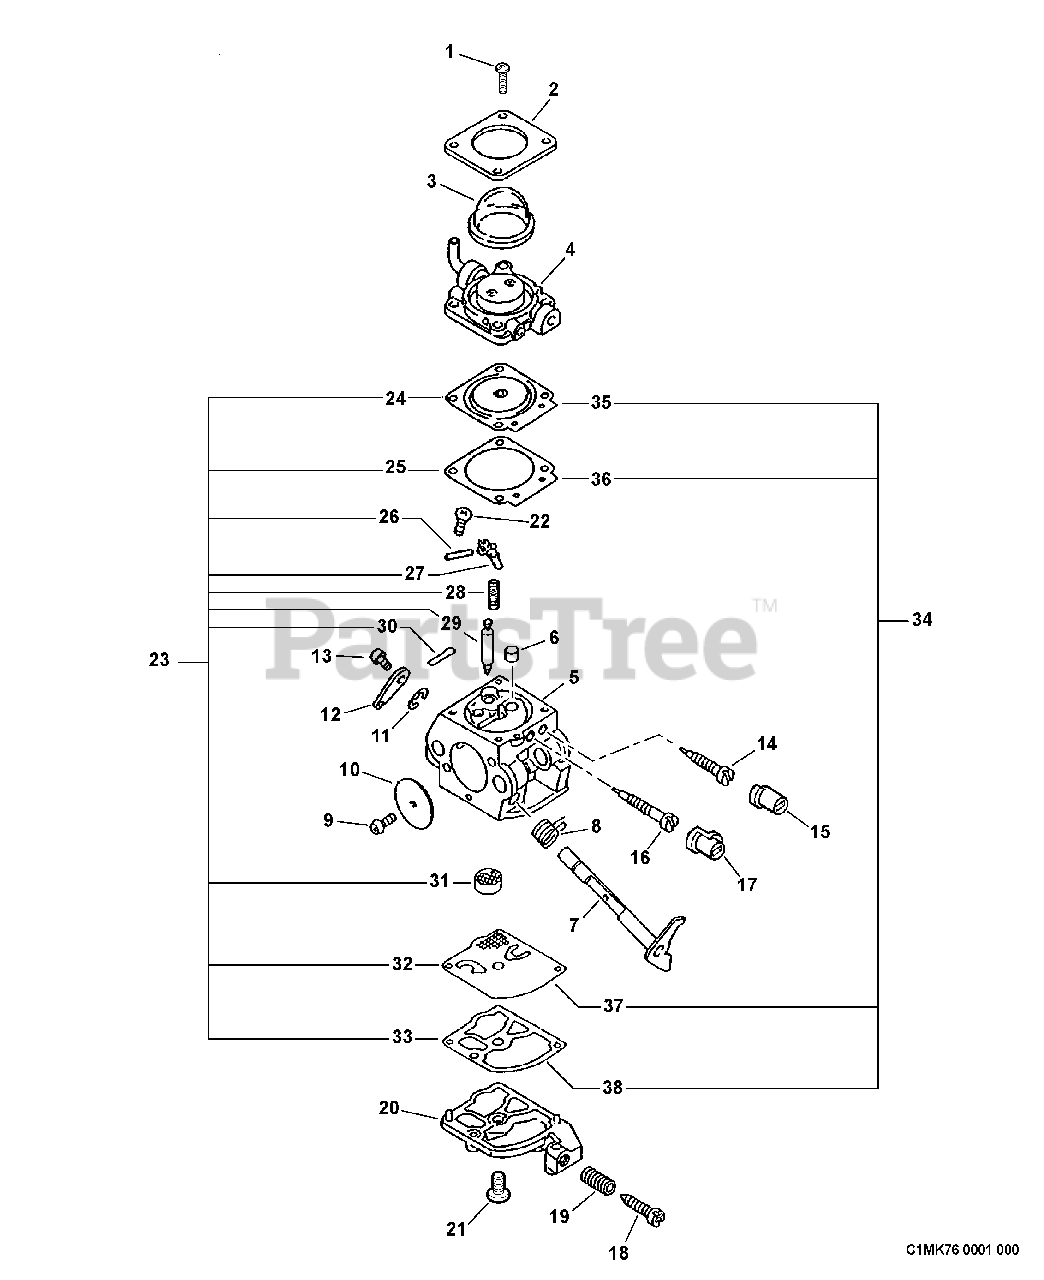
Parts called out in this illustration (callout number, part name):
1	SCREW, RETAINER
2	RETAINER, PURGE BULB
3	BULB, PURGE
4	BASE, PURGE
5	BODY, CARBURETOR
6	NOZZLE, CHECK VALVE
7	SHAFT, THROTTLE
8	SPRING, TRIGGER
10	VALVE, THROTTLE
11	RING, RETAINING
12	LEVER, THROTTLE
14	NEEDLE - HIGH SPEED
15	CAP, LIMITER
16	NEEDLE - LOW SPEED
17	CAP, LIMITER
18	SCREW, IDLE ADJUST
19	SPRING, IDLE ADJUST
20	COVER, FUEL PUMP
21	SCREW, PUMP COVER
22	SCREW, METERING LEVER PIN
23	REPAIR KIT
24	DIAPHRAGM, METERING
25	GASKET, METERING
26	PIN, METERING LEVER
27	LEVER, METERING
28	SPRING, METERING LEVER
29	VALVE, INLET NEEDLE
30	PLUG, WELCH
31	STRAINER
32	DIAPHRAGM, PUMP
33	GASKET, PUMP
34	DIAPHRAGM/GASKET KIT
35	DIAPHRAGM, METERING
36	GASKET, METERING
37	DIAPHRAGM, PUMP
38	GASKET, PUMP
